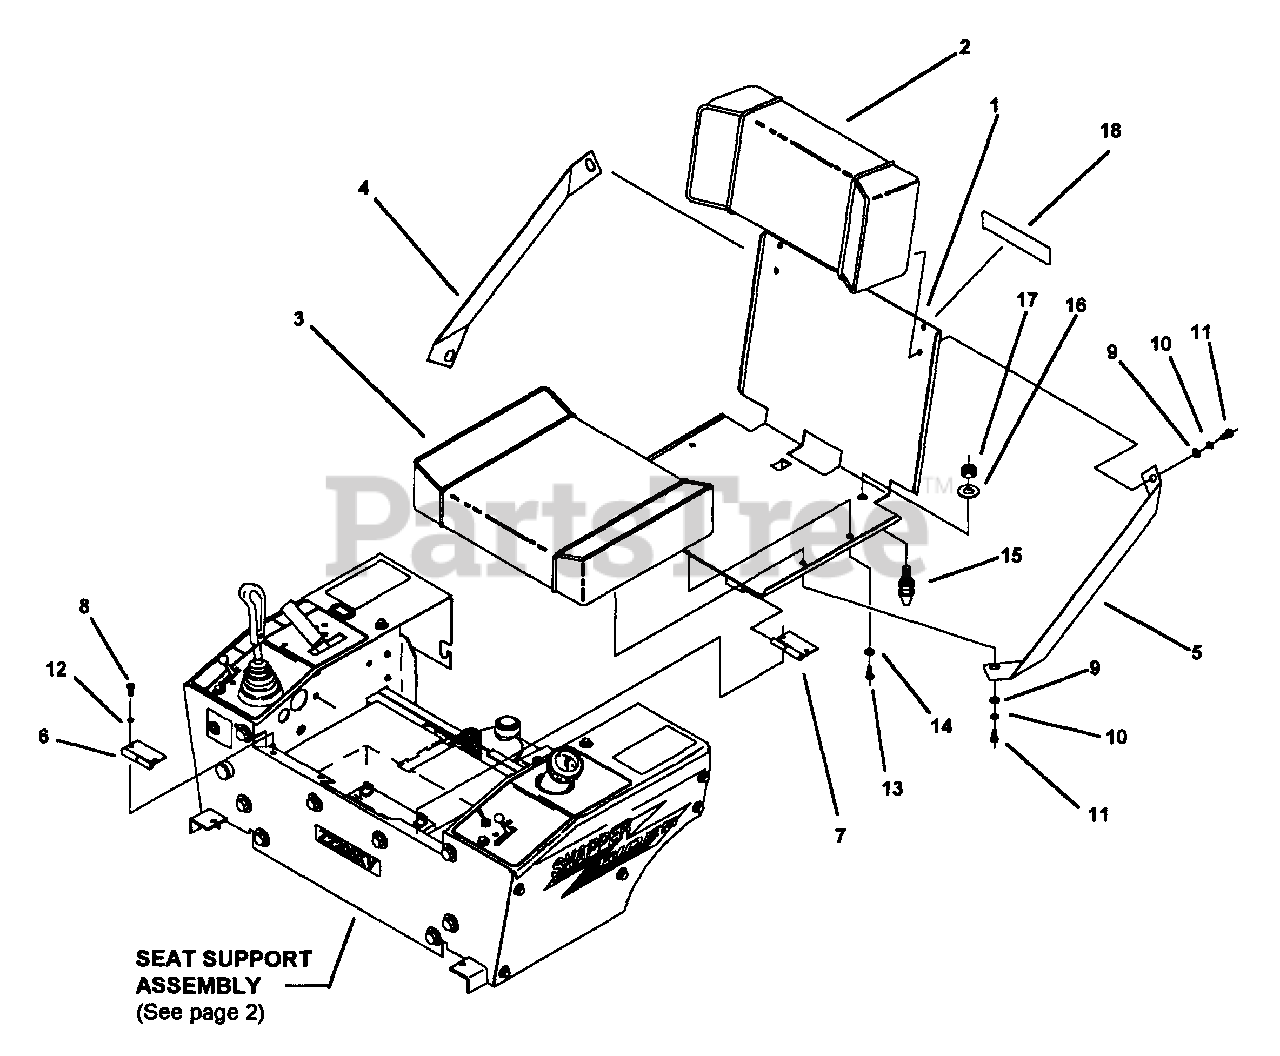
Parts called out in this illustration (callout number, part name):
1	SEAT BRACKET WLDT.
4	GUSSET, SEAT RIGHT
5	GUSSET, SEAT LEFT
6	HINGE, R.H.
7	HINGE, L.H.
8	BOLT, 1/4-20 X 3/4" GR.5
9	WASHER, FLAT STD. 5/16"
10	LOCKWASHER, 5/16" SPLIT SPRING
11	BOLT, 5/16-18 X 1" GR.5
12	LOCKWASHER, 1/4" SPLIT SPRING
15	LATCH PIN
16	WASHER, FLAT STD. 1/2"
17	NUT, HEX. 1/2-13 NYLOC
18	SNAPPER NAME PLATE
